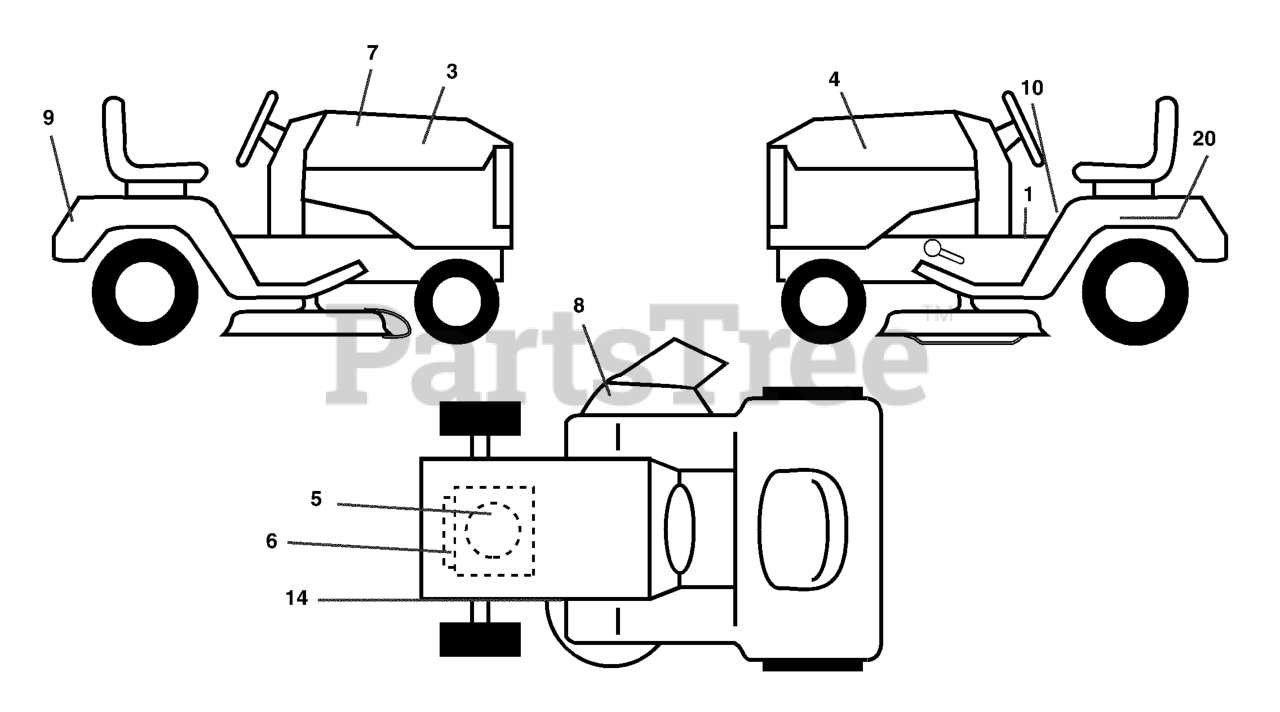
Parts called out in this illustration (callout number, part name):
1	DECAL FEND STLT OPER INST E/F
3	DECAL HOOD RH
4	DECAL HOOD LH
5	DECAL HOOD CUST. RESP.
6	DECAL ENGINE
7	DECAL REPLACEMENT
8	DECAL.WARN.KEEP.HAND.AWAY
9	DECAL, FENDER
10	DECAL FENDER DANGER
14	DECAL V-BELT SCHEMATIC
20	DECAL BTRY SYMBOLS
